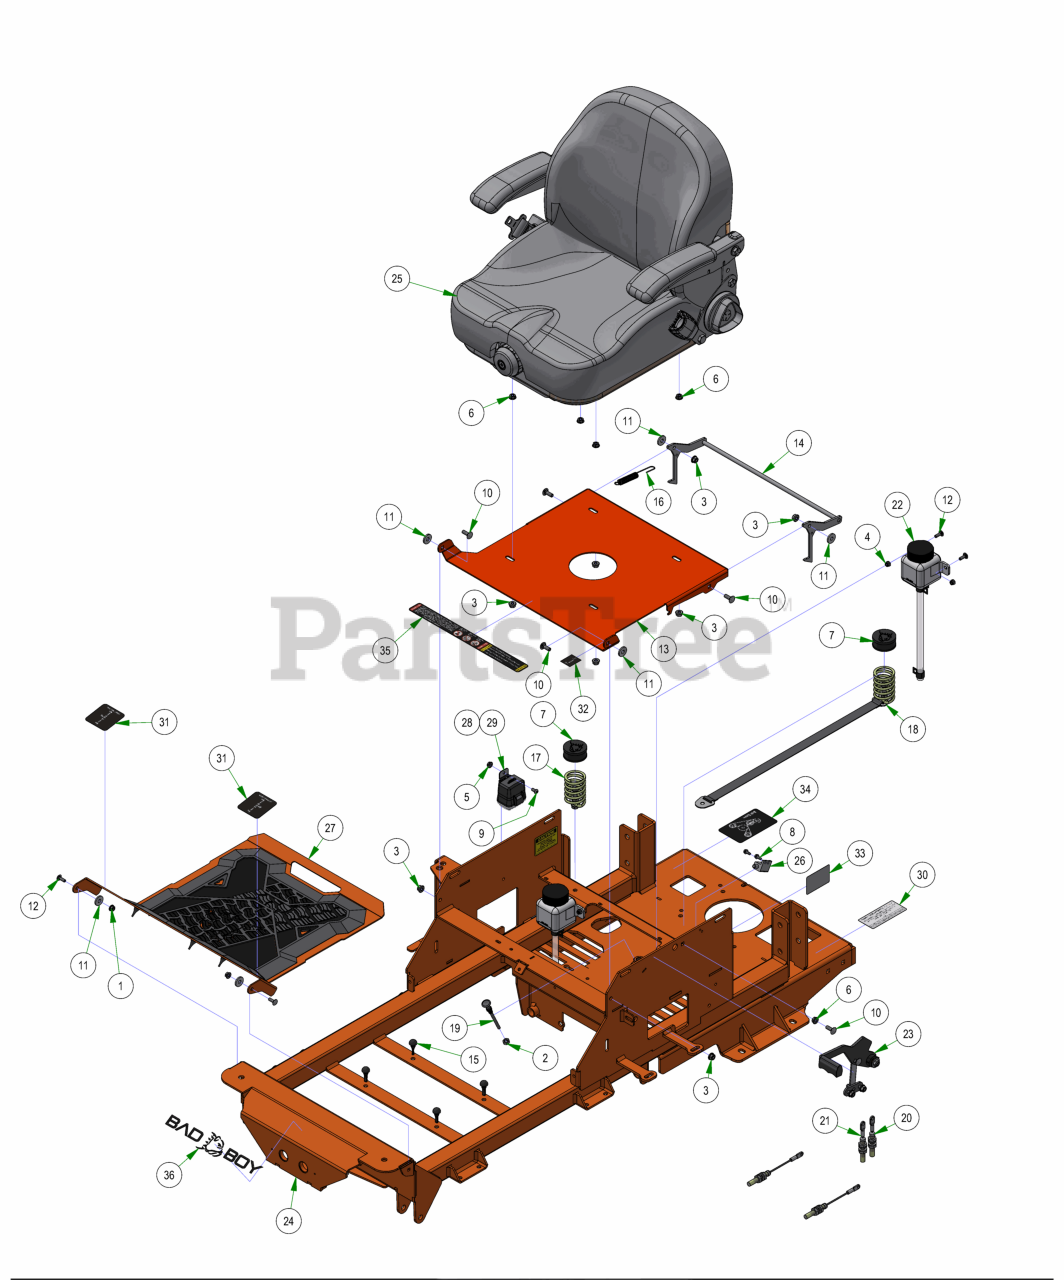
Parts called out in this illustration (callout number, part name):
1	1/4-20 NYL INSERT FLANGE LOCKNUT ZINC
2	3/8-24 HEX NUT ZINC YELLOW
3	5/16-18 NYLON INSERT FLANGE LOCKNUT ZINC
4	1/4-20 NYLON INSERT LOCKNUT ZINC
5	1/4-20 HEX SERRATED FLANGE NUT HARD/ZINC
6	5/16-18 HEX SERRATED FLANGE NUT HARD/ZINC
7	Spring Cap Cover
8	12-24 X 1/2 HEX WASHER UNLSOT F TCS ZINC
9	1/4-20 X 1/2 BUTTON SOCKET CAP SCREW 18-8 STAINLESS STEEL
10	5/16-18 X 7/8 CARRIAGE BOLT ZINC
11	.360 ID X .983 OD X .120 THICK FLAT WASHER NYLON
12	1/4-20 X 3/4 CARRIAGE BOLT (GR.5) ZINC
13	Seat Plate 2016
14	Seat Latch Rod Assembly
15	2023 Floor Board Rubber Bumper
16	Brake Spring
17	Seat Spring Assembly
18	2022 Mav/HD seat spring assembly with strap
20	2021 Load Balanced Brake Cable 1
21	2021 Load Balanced Brake Cable 2
22	Hydro Tank Assembly
23	2021 Load Balanced Brake Handle Assembly
24	2025 Maverick Frame
25	2025 Seats Inc Suspension
26	Safety Switch
27	2025 ZT/Mav/HD Floorboard Assembly
28	2024 Wiring Harness with Clips
29	2025 Wiring Harness with Clips and Lights
30	2025 EPA Build Date Punch Decal
31	2018 Maverick/2021 ZT Anti-Skid Steering Control Decals
32	2018 MZ/Magnum/ZT/MAV/Comp Out Brake Decal
33	Hydraulic Decal
34	Maverick Pump Belt Decal
35	Outlaw Warning Decal
36	Flying Bulldog Front Bumper Decal
